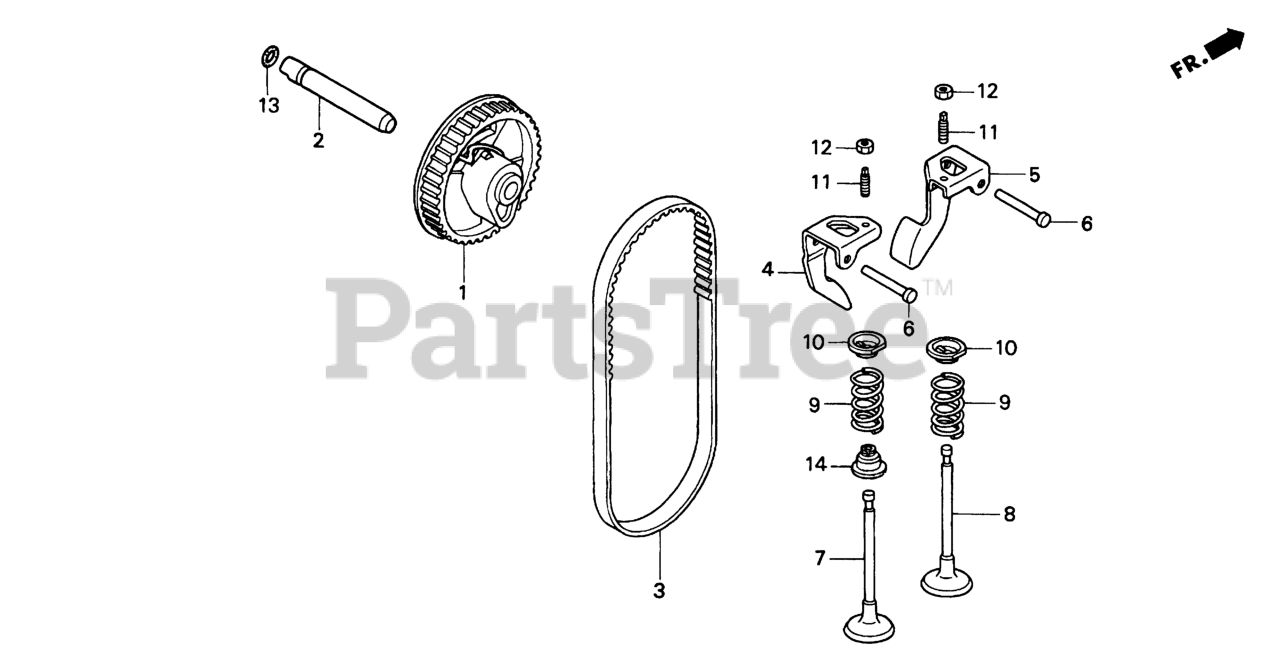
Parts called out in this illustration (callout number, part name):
1	PULLEY, CAMSHAFT
2	SHAFT, CAM PULLEY
3	BELT, TIMING (84HU7 G-200)
4	ARM, IN. VALVE ROCKER
5	ARM, EX. VALVE ROCKER
6	SHAFT, ROCKER ARM
7	VALVE, IN. (TECHNOSTAR)
8	VALVE, EX. (L8E)
9	SPRING, VALVE
10	RETAINER, VALVE SPRING (EXHAUST SIDE)
11	SCREW, TAPPET ADJ.
12	NUT, TAPPET ADJ.
13	O-RING (6.8X1.9) (ARAI)
14	SEAL, VALVE STEM
